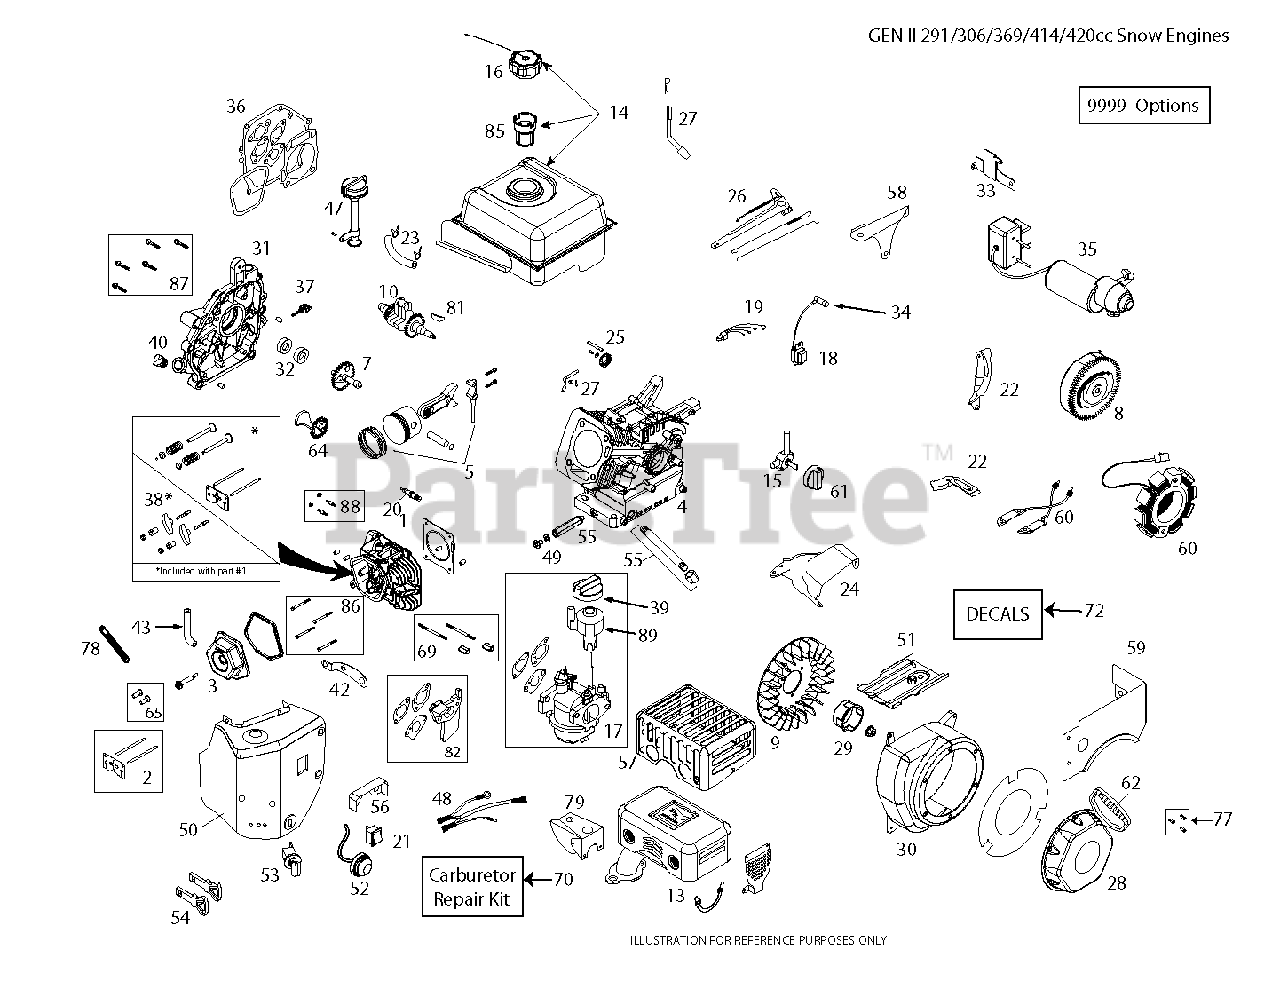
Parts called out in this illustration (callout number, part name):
1	CYL.HEAD.ASSY.45 DEG.NON-GEN
2	PUSH ROD TAPPET KIT
3	VALVE.COVER.LCT.414CC.
4	CYLINDER ASSY
5	PISTON.AND.ROD.ASSY(SK4141400)
7	CAMSHAFT(SK4141600)
8	FLYWHEEL.EL.ST.SKSN4408.1
9	FLYWHEEL.FAN(SK4144000)
10	CRANKSHAFT KEYED #18 LCT 414C
13	MUFFLER (SKSN2210.1)
14	FUEL TANK ASSY 414C LCT
15	FUEL.PETCOCK.SNOW(SKSN4900)
16	FUEL.TANK.CAP.SNOW(SKSN4301)
17	CARBURETTOR 414 W/IDLEDOWN
18	IGNITION.COIL.(CDI).291-414CC
20	SPARK.PLUG(SK2911550)
21	ON/OFF.SWITCH.SNOW(SKSN4403)
22	SHIELD.U/FYWHL.CHARG(SKSN4604)
23	FUEL HOSE KIT
24	RP TOP SHIELD
25	GOVERNOR.GEAR.ASSY(SK4142900)
26	RECOIL.START.ASSY.SNW(SKSN4600
27	GOVERNOR.SHAFT(SK4143100)
28	STARTER RECOIL LCT 414
29	STARTER.CUP.SML.SNOW(SKSN4601)
30	BLOWER HSG.414 LCT GLOSS BLACK
31	CRANKCASE.COVER.LCT.414CC.HIGH
32	OIL SEAL KIT NON-GENERATOR
33	ELECTRIC.START.BRKT(SKSN4405)
34	SPARK.PLUG.BOOT.SNW,SKSN4691.1
35	STARTER EUROPEAN 230V ELECTRIC
36	KIT.ENGINE GASKET.LCT.414CC
37	DIPSTK.OIL.BLK.LCTSK4143711.1
38	ROCKER ARM KIT
39	CHOKE.KNOW.SNOW(SKSN4500)
40	NONREMVABLE.OIL.PLUG(SK4143715
42	CDI.BOX.BRKT.SNOW(SKSN4402)
43	TUBE.BREATHER.LCT.219CC/414CC
47	HIGHOIL.FILL.ASSY.KIT(SKSN4911
48	WIRE.HARNESS(SKSN4406)
49	OIL.DRAIN.PLUG
50	BOX HEATER ASM 414 LCT
51	SHIELD.CYLINDER.SNOW(SK4141010
52	PRIMER.BULB.ASSY(SKSN4304)
53	KEY.SWITCH.ASSY.SNOW(SKSN4401)
54	KEY SET(2 KEYS) SKSN0407.1
55	OIL PIPE DRAIN EXTENDED.LCT SK
56	SHIELD.VAPOR(SKSN4606)
57	CE COMPLIANT MUFFLER SHEILD
58	PLATE.GOVERN.LINK.S
59	FUEL TANK SKIRT 414 LCT GLOSS
60	ALTERN.60WATT.SKSN2402.1
61	FUEL KNOB-SNOW
62	HANDLE.RECOIL.DELUXE.LCT
64	COUNTER WEIGHT KIT
65	TAPPET KIT.LCT.SK2911005.1
69	STUD.CARB.MOUTING.KIT.414CC
70	CARBURETTOR REPAIR KIT 291CC/4
77	BOLT.KIT.RECOIL.LCT.ALL.ENGINE
78	STRAP.RETAINING.TUBE.BREATHER.
79	SHIELD CARBURRETOR COVER 414
81	KEYS.FLYWHEEL.136/291CC.5PACK
82	SPACER.CARBURETOR.414CC.LCT
85	STRAINER.FUEL.TANK.LCT.208CC
86	KIT.BOLT.CYLINDER.HEAD.(4PC)
87	KIT.BOLT.CRANKCASE.COVER.414CC
88	STUD.MUFFLER.KIT.LCT
89	KNOB LCT.SKSN5325.1 SPEED
9999	HIGH ALTITUDE JET 6000FT
